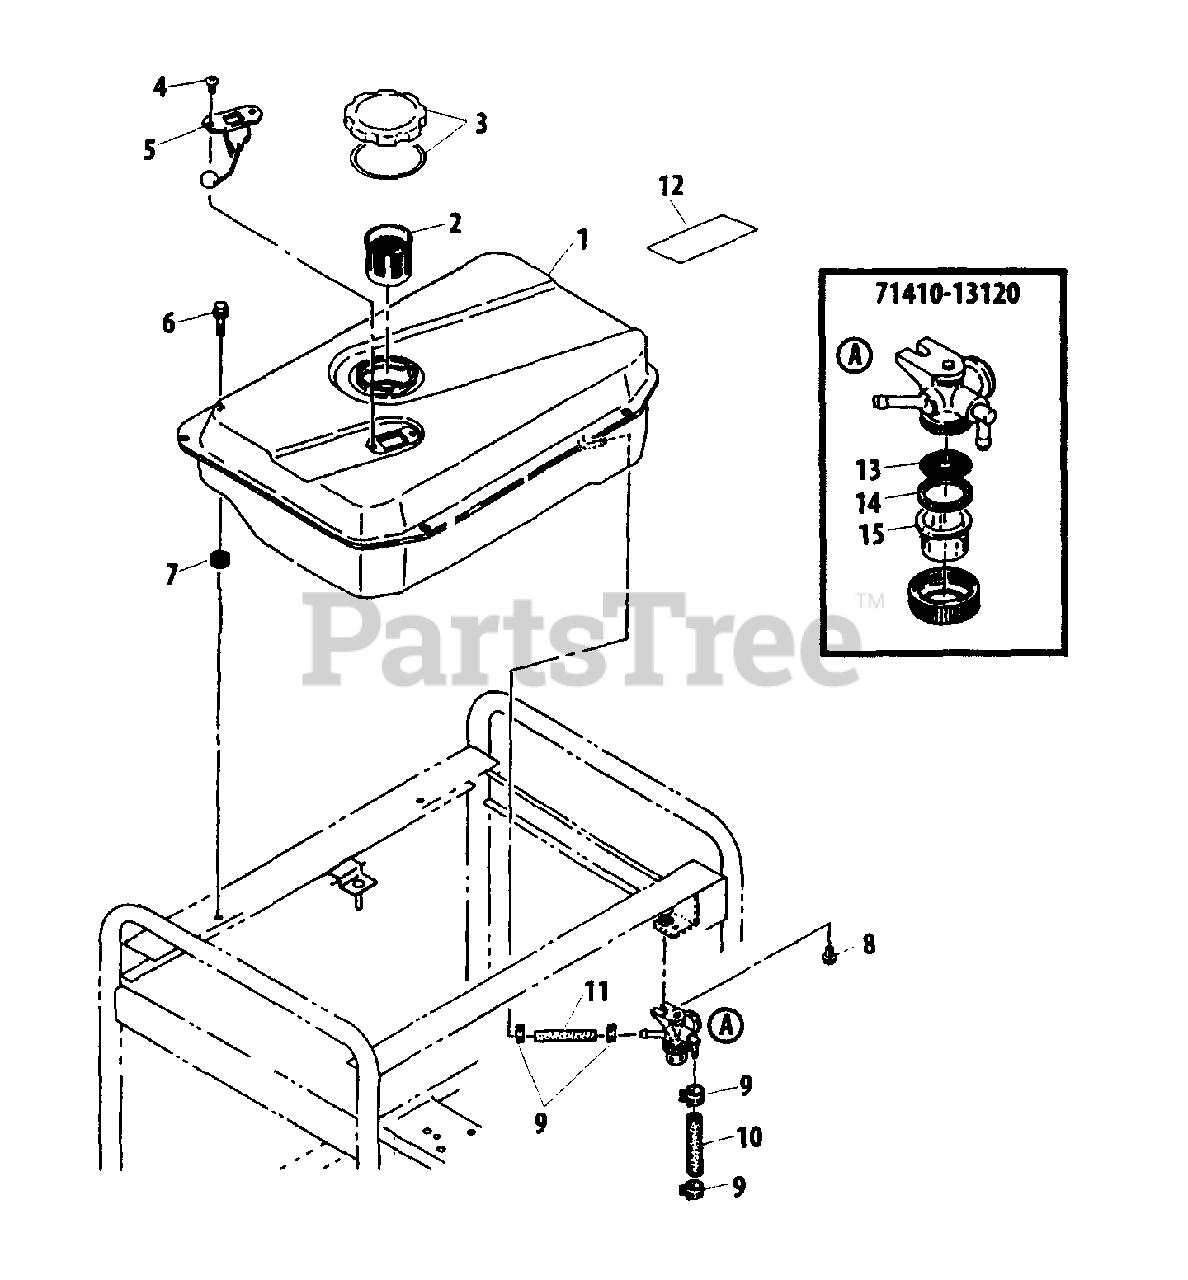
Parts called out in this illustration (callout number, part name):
1	TANK, FUEL
2	STRAINER, FUEL
5	GAUGE, FUEL
9	CLAMP, HOSE
10	FUEL TUBE 6×12×210 MM
11	FUEL TUBE 6×12×80 MM
12	LABEL - CAUTION
71410-13120	FUEL VALVE ASSY
